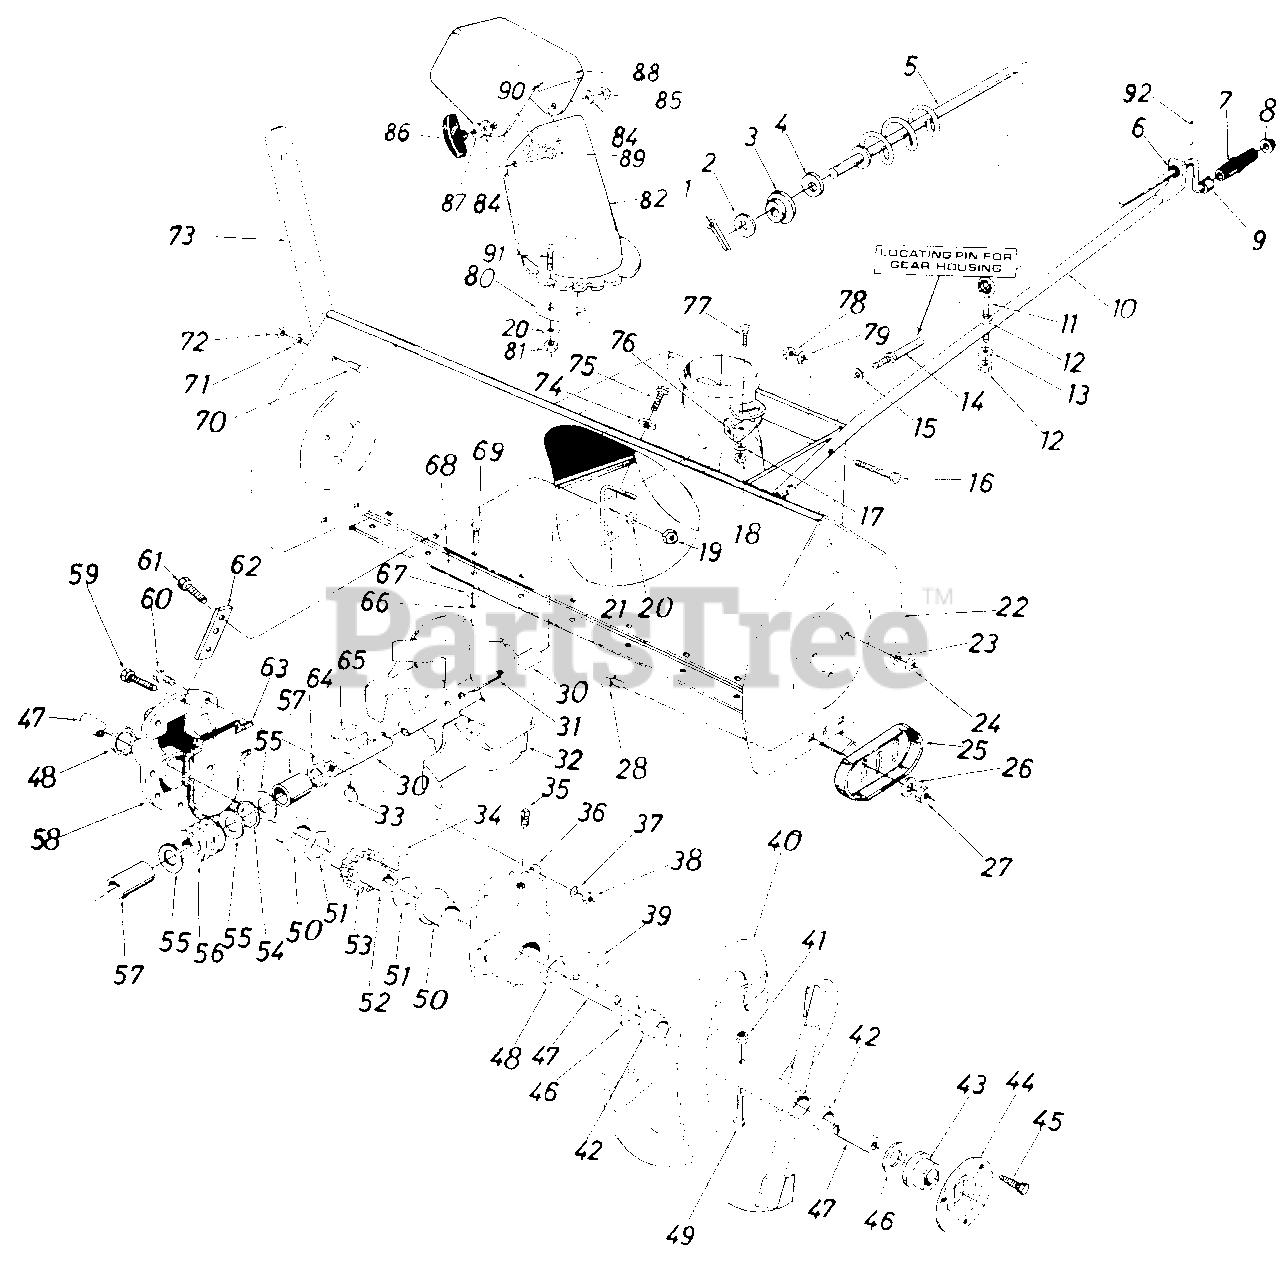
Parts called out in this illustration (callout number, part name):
1	Cotter Pin
2	Fl.-Wash. .39" I.D. x .62" O.D.
3	Plastic Bushing
4	Fl.-Wash. .385" I.D. x .62" O.D.
5	Chute Crank Ass'y.
6	Plastic Bushing
7	Knob (Black)
8	Push Nut 3/8" Rod
9	Spacer .385 I.D. x .50" I.D.
10	Chute Crank Support Tubing
11	Eyebolt
12	Hex Nut 5/16-18 Thd.
13	Bell.-Wash. .345" I.D. x .88"O.D.
14	Stud 3/8-16 x 2.75 " Lg.
15	Bell.-Wash. .400" I.D. x .88"O.D.
16	Hex Bolt 3/8-24 x 1.25" Lg.*
17	Bell.-Wash. .345" I.D. x .88"O.D.
18	Hex Nut 5/16-18 Thd.*
19	Hex Nut 1/4-28 Thd.
20	Bell.-Wash. .265" I.D. x .75"O.D.
22	45" Snow Blower Housing Ass'y.
23	L.-Wash. 5/16" I.D.*
24	Hex Nut 5/16-18 Thd.*
25	Slide Shoe
26	Bell.-Wash. .400" I.D. x.88"O.D.
27	Hex Jam Nut 3/8-16 Thd.
28	Carriage Bolt 3/8-16 x .62" Lg.*
30	Blower Axle .875" Dia. x 14.75" Lg.
31	Spring Pin Spir. 5/16" Dia. x 1.75" Lg.
34	#91 Woodr-Key 1/4 x 3/4" Dia. (HDN)
35	Vent Plug
36	Comp. Gear Hsg. Half-L.H.
37	Spr.-Wash. .32" I.D. x .62" O.D.
38	Hex Ins. L.-Nut 5/16-18 Thd.
39	#91 Woodr-Key 1/4 x 3/4" Dia. (HDN)
41	Hex Ins. L.-Nut 5/16-18 Thd.
42	Plastic Bushing
43	Flange Brg. w/flats 1" I.D.
44	Bearing Housing
45	Hex Sems Bolt 5/16-18 x .75" Lg*
46	Fl.-Wash. 1.00" I.D. x 1.75" o J
47	Spiral Axle
48	Flange Bearing 1.503" I.D.
49	Shear Bolt 5/16-18 x 1.75" Lg.
50	Oil Seal 1.50" I.D.
51	Fl.-Wash.1.50" I.D. x 2.00" O.D
52	Worm Gear Shaft
53	Double Threaded Worm Gear -L. H .
54	Thrust Brg. - .88" I.D. x 1.44" 0. D .
55	Fl.-Wash..88" I.D. x 1.4" O.D.
56	Double Threaded Worm - L.H.
57	Sleeve
58	Complete Gear Hsg. Half - R.H.
59	Hex BoIt5/16-18xl.25" Lg.*
60	Hex Bolt 5/16-18 x 1.0" Lg. (Grade 5)
61	Hex Bolt 1/4-28 x .75" Lg.
62	Gear Housi ng Support Plate
63	Rubber Gasket
64	Oil Seal - .875" I.D.
65	#9 Hi-Pro Key 3/16 x 3/4" Dia. (HT.)
66	Hex Nut 5/16-18 Thd.*
67	L.-Wash. 5/16" I.D.*
69	Carriage Bolt 5/16-18 x 1.00" Lg.*
70	Carriage BoIt 5/16-18 x .62 " Lg.*
71	L.-Wash. 5/16" I.D.*
72	Hex Nut 5/16-18 Thd.*
73	Guide Blade
74	Bell.-Wash. .345" I.D. x .88" O.D.
75	Hex Wash. Hd. AB Tap Scr 5/16 x .75" Lg.
77	Carriage Bolt 5/16-18 x .75" Lg.*
78	Hex Ins. L.-Nut 3/8-24 Thd.
79	L.-Wash. 3/8" I.D.*
80	Chute Flange Keeper
81	Hex Nut 1/4-20 Thd.*
82	Chute Ass'y. w/Chute Guard
84	Bell.-Wash. .345" I.D. x .88"O.D.
85	Hex Cent. L.-Nut 5/16-18 Thd.
86	Knob Handle
87	Bell.-Wash. .345" I.D. x .88" O.D.
88	Top Chute Ass'y. I
89	Carriage Bolt 5/16-18 x 1.00" Lg.*
90	Carriage Bolt 5/16-18 x .62" Lg.*
91	Truss Mach. Scr. 1/4-20 x .75"
92	Roll Pin .12 Dia. x .63"
